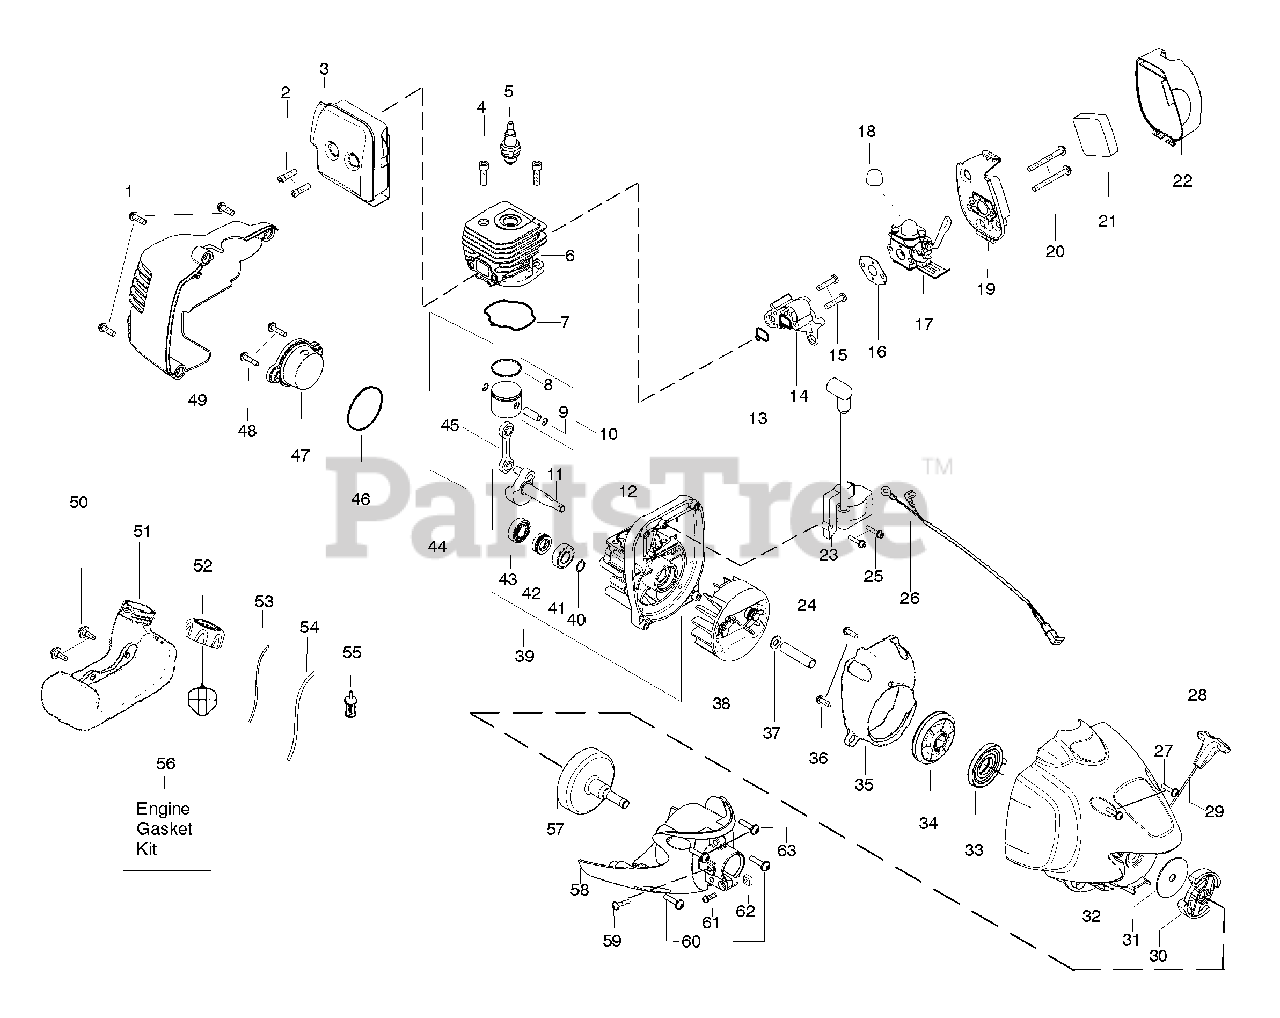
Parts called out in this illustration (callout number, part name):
2	Bolt-Muffler
3	Assy-Muffler/Shield
4	Screw-Cylinder
5	Spark Plug
6	Cylinder
7	Seal-Cylinder
8	Piston Ring
9	Retainer-Piston Pin
10	Kit - Piston
11	Assy-Crankshaft
12	Assy-Crankcase
13	Seal-Cyl/Carb.
14	Adapter-Carb.
16	Gasket-Carb.
17	Kit-Carb.
18	Bulb-Purge
21	Foam-Air Filter
22	Cover-Air Box
23	Ignition Module
24	Spacer-Flywheel
26	Assy-Switch wire
28	Handle-Starter
29	Kit - Rope
30	Assy-Clutch
31	Washer-Clutch
32	Assy.-Fan Hsg
33	Spring-Starter
34	Kit-Starter Pulley
37	Washer-Clutch Flat
38	Assy-Flywheel
39	Assy-C'case & C'shaft
40	Retain. Ring-C'shaft
41	Outer Bearing
42	Seal-C'shaft
43	Inner Bearing
44	Kit-piston/rod
45	Kit-Conn. Rod
46	O-Ring-C'case
47	Assy-Plug
49	Shroud-Rear
50	Retainer-Tank
51	Assy-Fuel Tank
52	Assy-Fuel Cap
53	Kit-Fuel Line
54	Kit-Fuel Line
55	Assy-Fuel Pickup
56	Kit-Engine Gasket
57	Assy-Clutch Drum
58	Assy-Clutch Cover
59	Screw-Align
61	Screw 12-24
62	Nut 12-24
